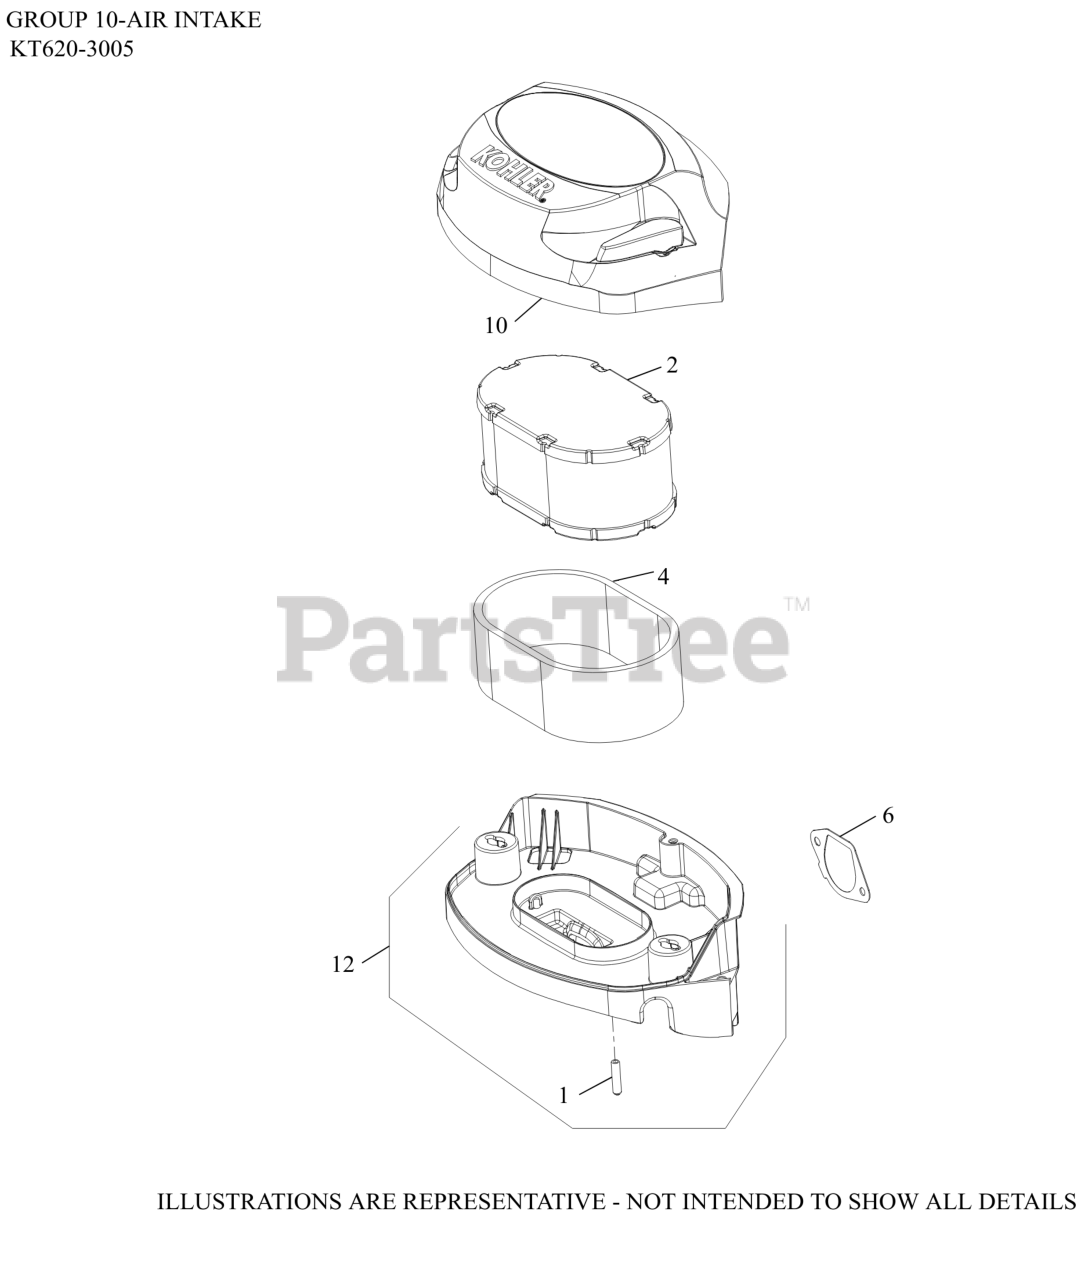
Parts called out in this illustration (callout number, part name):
1	CAP, MASKING
2	ELEMENT, AIR FILTER
4	ELEMENT, PRE-CLEANER
6	GASKET, AIR CLEANER BASE
10	COVER ASSY, AIR CLEANER
12	BASE ASSY, AIR CLEANER
